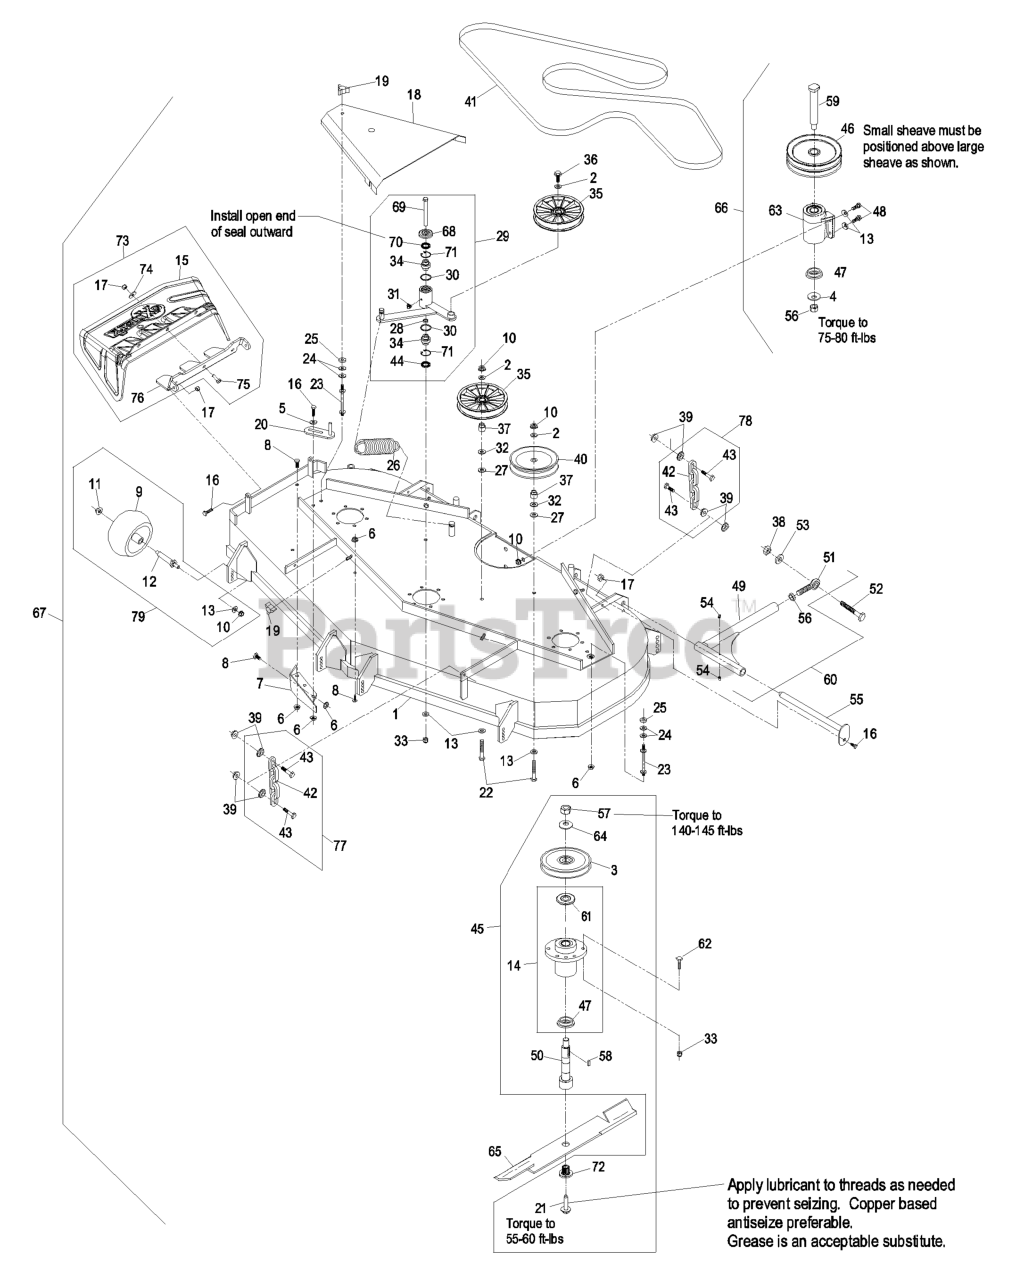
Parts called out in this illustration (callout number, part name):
1	ASM,DECK W/DECALS LZ524
2	WASHER-FLAT
3	SHEAVE,BLADE DRIVE 6.30
4	WASHER-SPRING
5	WASHER-SPRING
7	WLD,BAFFLE DISCHARGE
8	SCREW-HH
9	ROLLER-SCALP, ANTI
10	NUT-HHF, WHIZ
11	Nut-Nyloc 3/8-16 Flg
13	WASHER-BELLEVILLE
14	KIT, CUTTER HOUSING
15	CHUTE,DISCHARGE
16	SCREW-HH
17	NUT-LOCK, NI
18	SHIELD,BELT 52
19	KNOB-3 PRONG
20	GUIDE-BELT
22	BOLT-CARR
23	STUD-SHIELD, BELT (SHORT)
24	WASHER-FLAT
29	KIT,DECK IDLER LZ/XP
31	FITTING-GREASE, 90 DEG
32	WASHER-FLAT
33	NUT-LOCK, NI
34	BEARING-SPHERICAL
35	PULLEY,IDLER 6"
36	SCREW-HHF
37	BUSHING-IDLER
38	NUT-HEX
40	PULLEY-IDLER
41	BELT,BLADE DRIVE 52
42	CHAIN-LIFT, DECK
43	SCREW-HH
44	SEAL-LIP, DOUBLE
45	ASM, CUTTER HSG COMPLETE
46	SHEAVE,JACKSHAFT - DBL
47	SPACER-GUARD, BOTTOM
48	SCREW-HH
49	STRUT-DECK
50	KIT, SPLINED SPINDLE 103-
51	BALLJOINT-SPHERICAL
52	SCREW-HH
53	WASHER-LOCK
54	FITTING-GREASE
55	PIN-STRUT
56	NUT-HEX
59	JACKSHAFT
60	STRUT ASM
61	GUARD-BEARING, TOP
62	SCREW-HH
63	KIT, JACKSHAFT ASSY
66	KIT,JACKSHAFT 52-3750
67	Asm, Deck Complete
68	GUARD-TOP
69	SCREW-HH
70	SEAL-LIP, SINGLE
71	RING-SNAP
72	BUSHING,SPLINED
74	WASHER-FLAT
75	SCREW-CARR
76	BRACKET,DISCHARGE CHUTE
77	DECK CHAIN ASM
78	DECK CHAIN ASM
